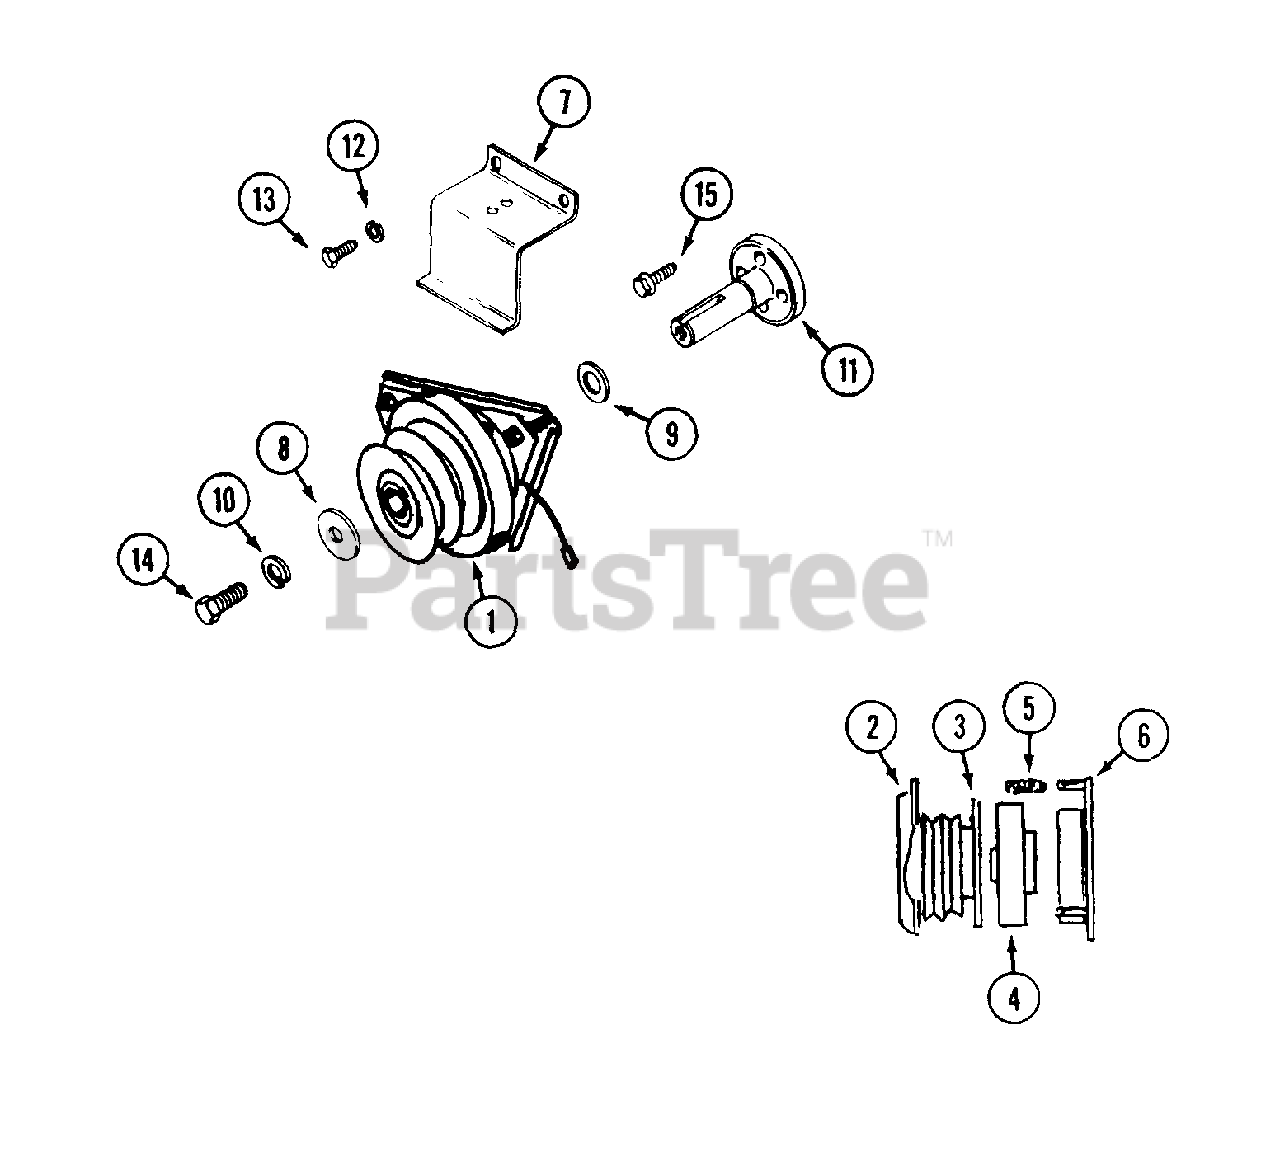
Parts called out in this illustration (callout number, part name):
1	CLUTCH - electric
2	BRAKE - clutch
3	ARMATURE - clutch
4	ROTOR - clutch
5	KIT - spring and nut (3 each)
6	COIL - clutch
7	BRACKET - clutch stop
8	WASHER - .41" x 1.75" x 1/4"
9	WASHER - thrust 1" x 1.5"
10	LOCKWASHER - 3/8"
11	ADAPTER - clutch
12	LOCKWASHER - 5/16"
13	BOLT - M8 - 1.25 x 16
14	BOLT - 3/8" -24 x 1-1 /4"
15	SCREW - M10 - 1.25 x 34
